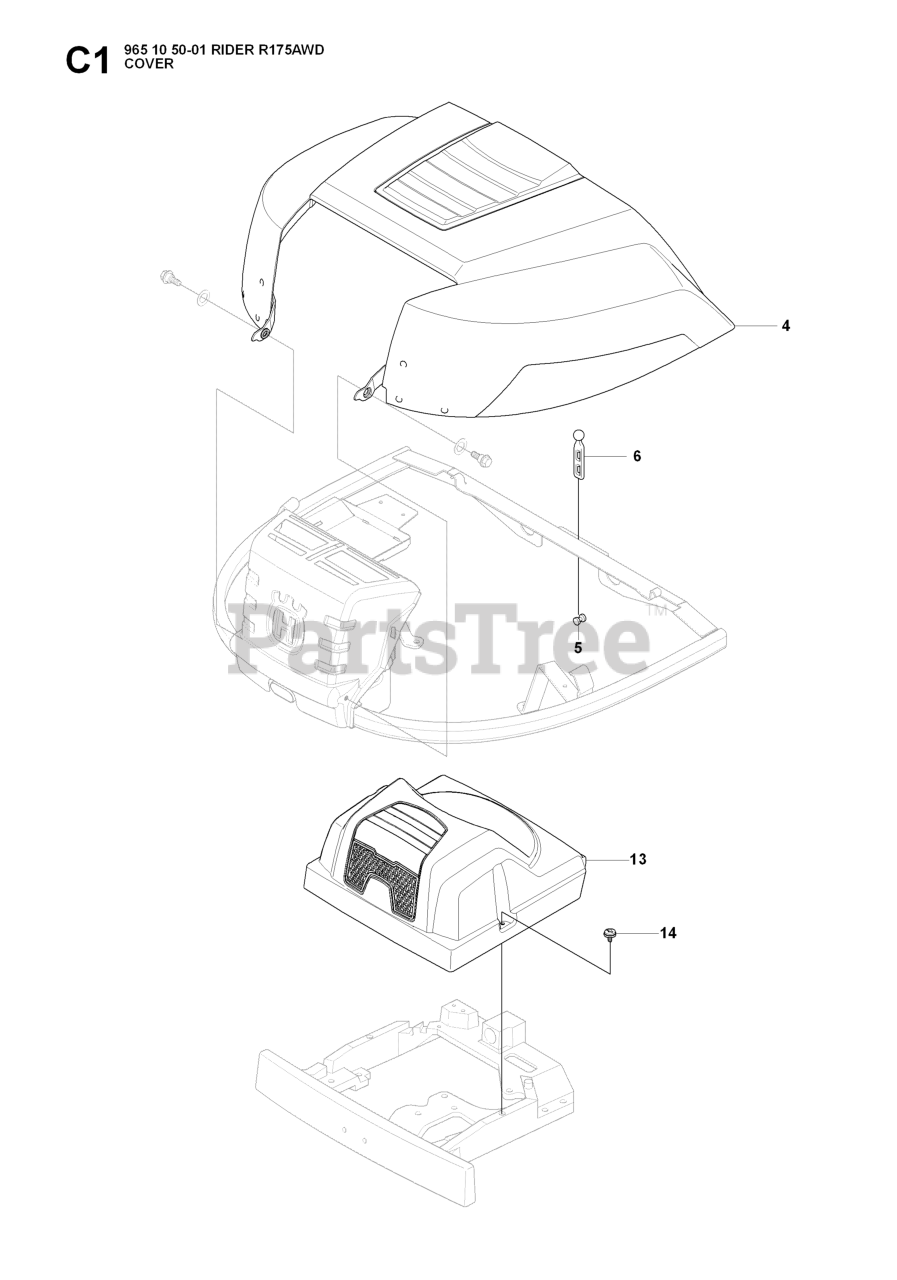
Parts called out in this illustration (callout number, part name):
4	ENGINE HOOD ASSY
6	Support Strap
13	COVER
